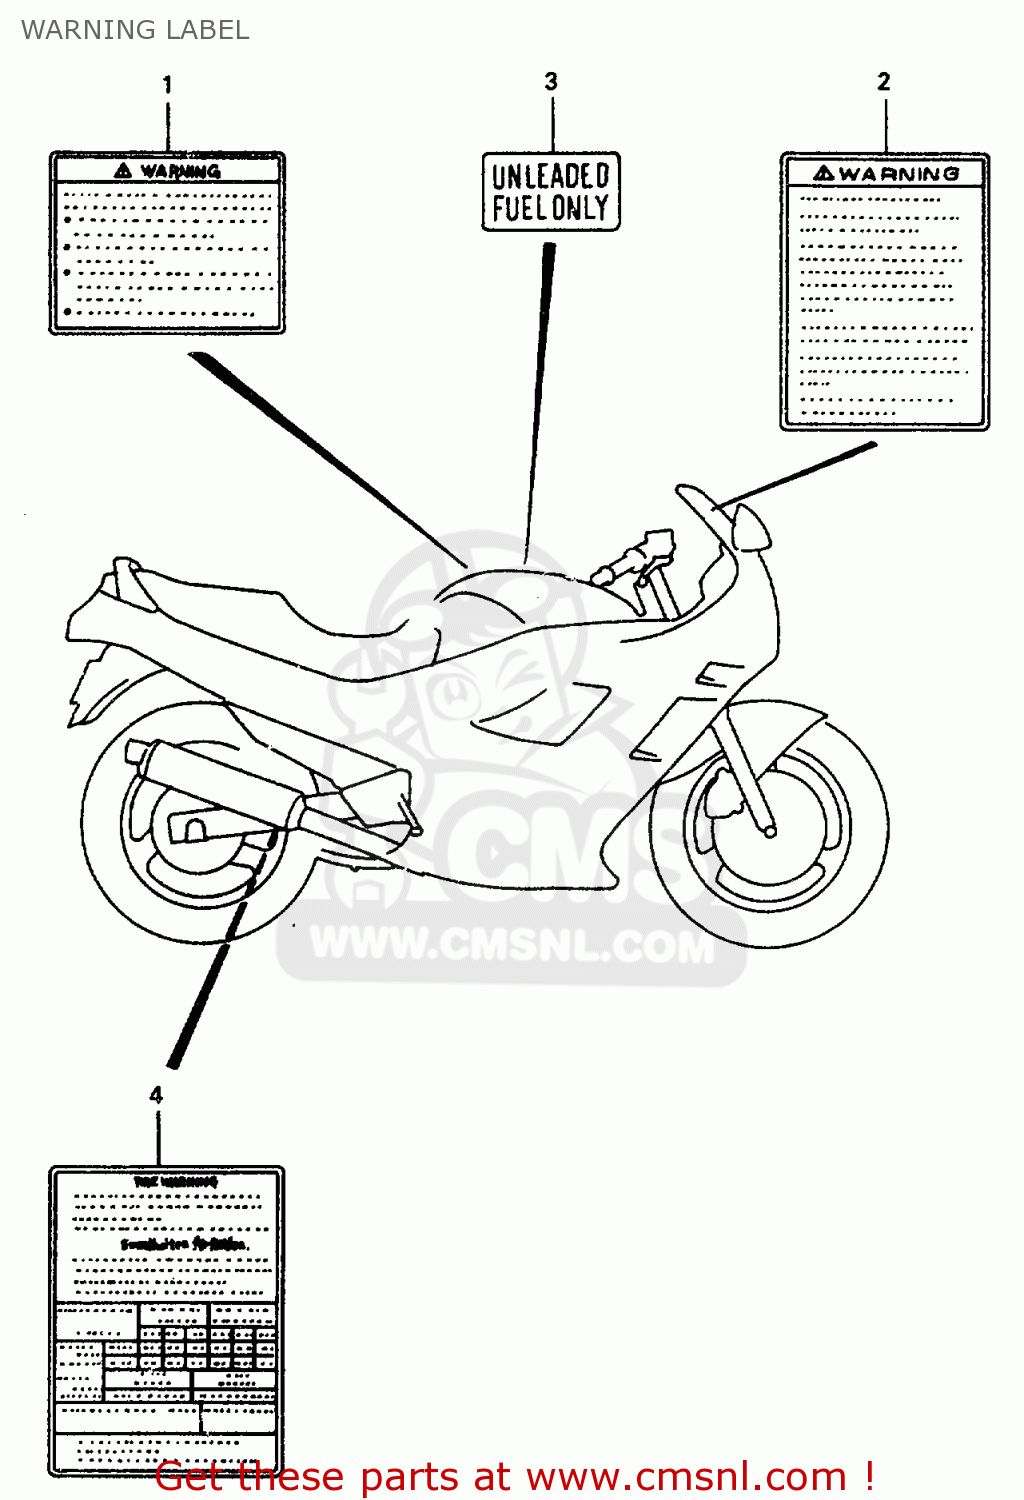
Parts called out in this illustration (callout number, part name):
1	LABEL,WARNING
2	LABEL (WARNING SCREEN)
3	LABEL,CAUTION
4	LABEL, TIRE AIR
